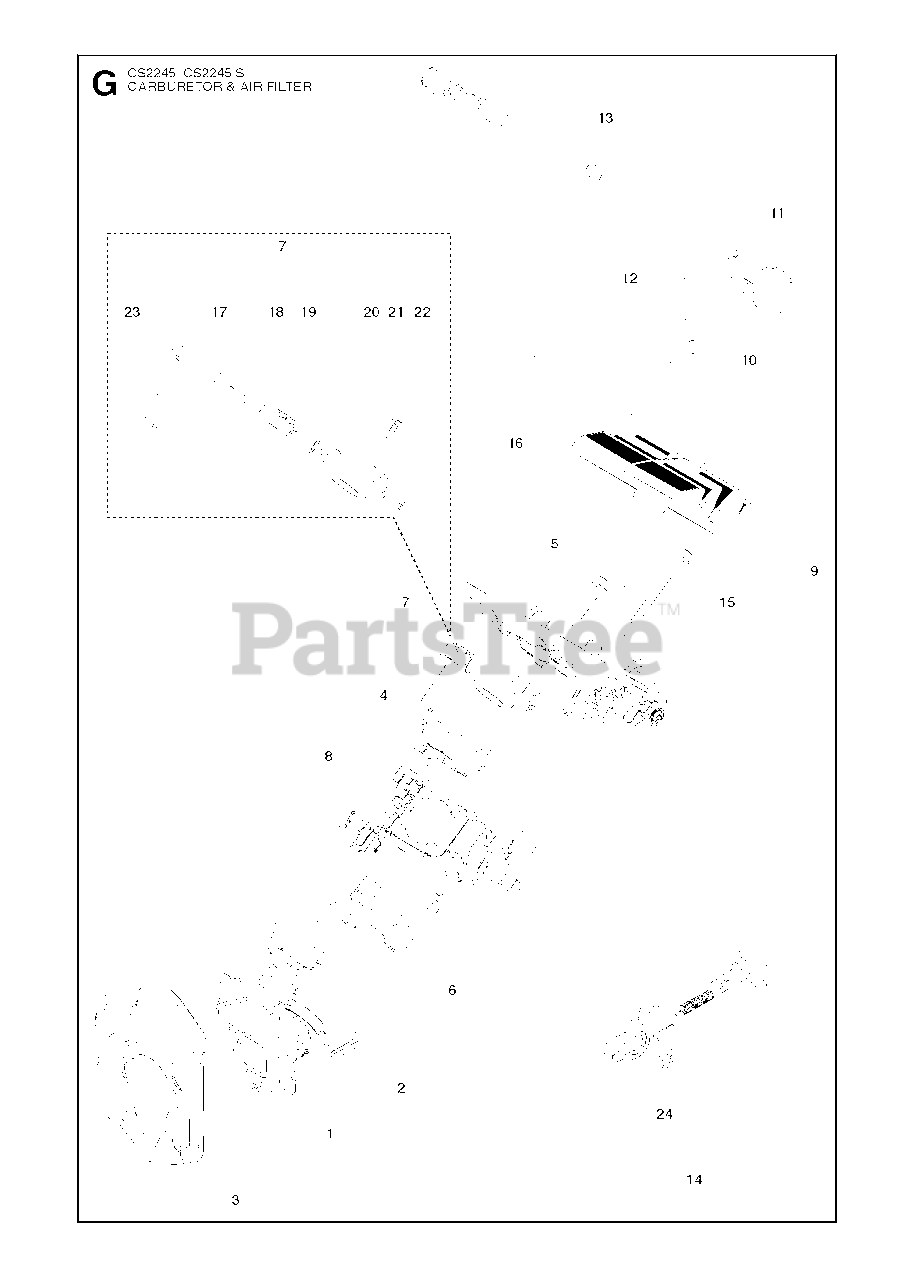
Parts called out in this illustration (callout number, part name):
1	INLET PIPE ASSY
3	INTERMEDIATE WALL
8	CARBURETOR
9	%FILTER HOLDER
10	SHACKLE
11	AIR PURGE BUBBLE
13	RP RETURN HOSE
16	AIR FILTER - NYLON (80)
16	AIR FILTER - NYLON (44)
16	AIR FILTER - FELT
17	SHAFT ASSY
18	SPRING
19	COLLAR
20	VALVE
21	SCREW
22	CLIP
23	ROD
24	LOCK WASHER
